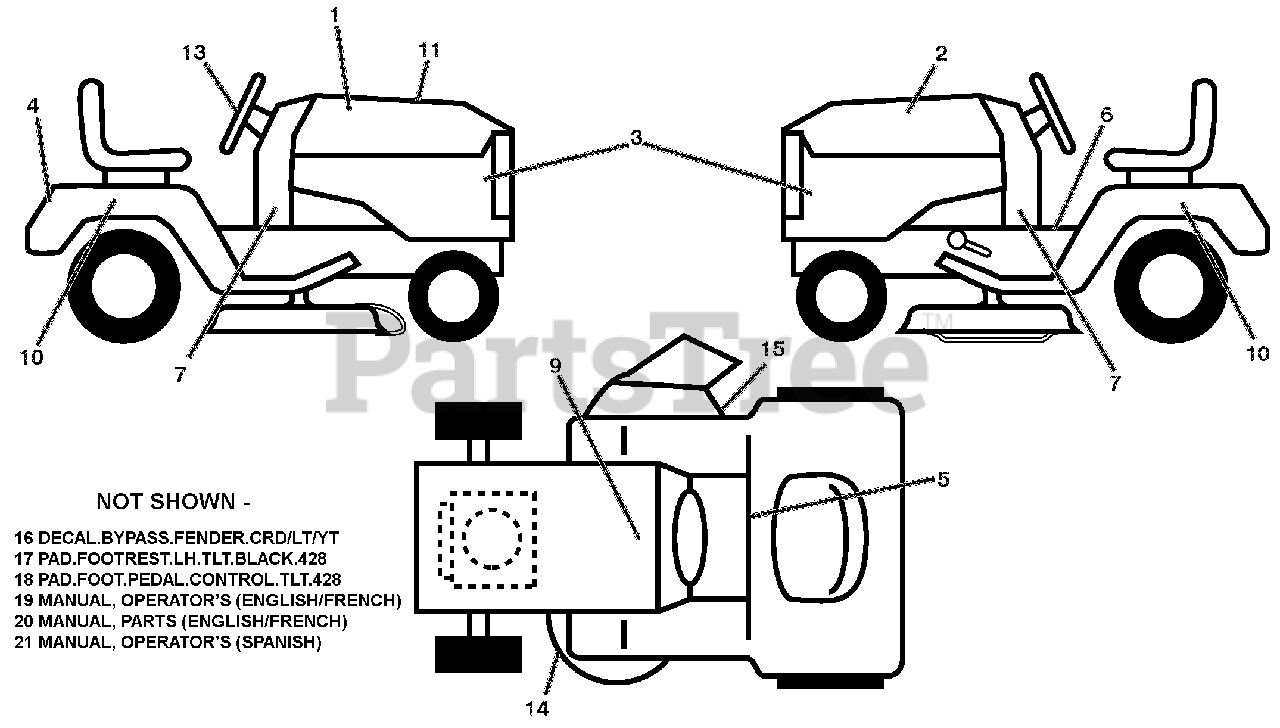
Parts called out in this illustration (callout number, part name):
1	DECAL.HOOD.RH.PRECISION.ARIENS
2	DECAL.HOOD.LH.PRECISION.ARIENS
3	DECAL.SDPNL.PWRDBY KOHL.ARIENS
4	DECAL.FENDER.REAR.ARIENS
5	Decal, Flag
6	DECAL.FENDER.WARNING.ENG/FR.07
7	DECAL.DASH.LWR.25HP.ARIENS
8	DECAL.MOWER.WARN.KEEP HAND AWY
9	DECAL.BAT.DAN/POI P/L SYM.WPN
10	DECAL.FENDER.SIDE.HYDRO.ARIENS
11	DECAL.RPL.KH.TWIN.TLW.54.0510
13	DECAL.WHEEL.STEER.ARIENS
14	DECAL.MOWER.SCH.48/54.PREM.
15	DECAL.MOWER.CAUTION.TENSION.AR
16	DECAL.BYPASS.FENDER.CRD/LT/YT
17	PAD.FOOTREST.LH.TLT.BLACK.428
18	PAD.FOOT.PEDAL.CONTROL.TLT.428
19	MANUAL, OPERATOR'S (ENG/FRA)
20	MANUAL, PARTS (ENGLISH/FRENCH)
21	MANUAL, OPERATOR'S (SPANISH)
